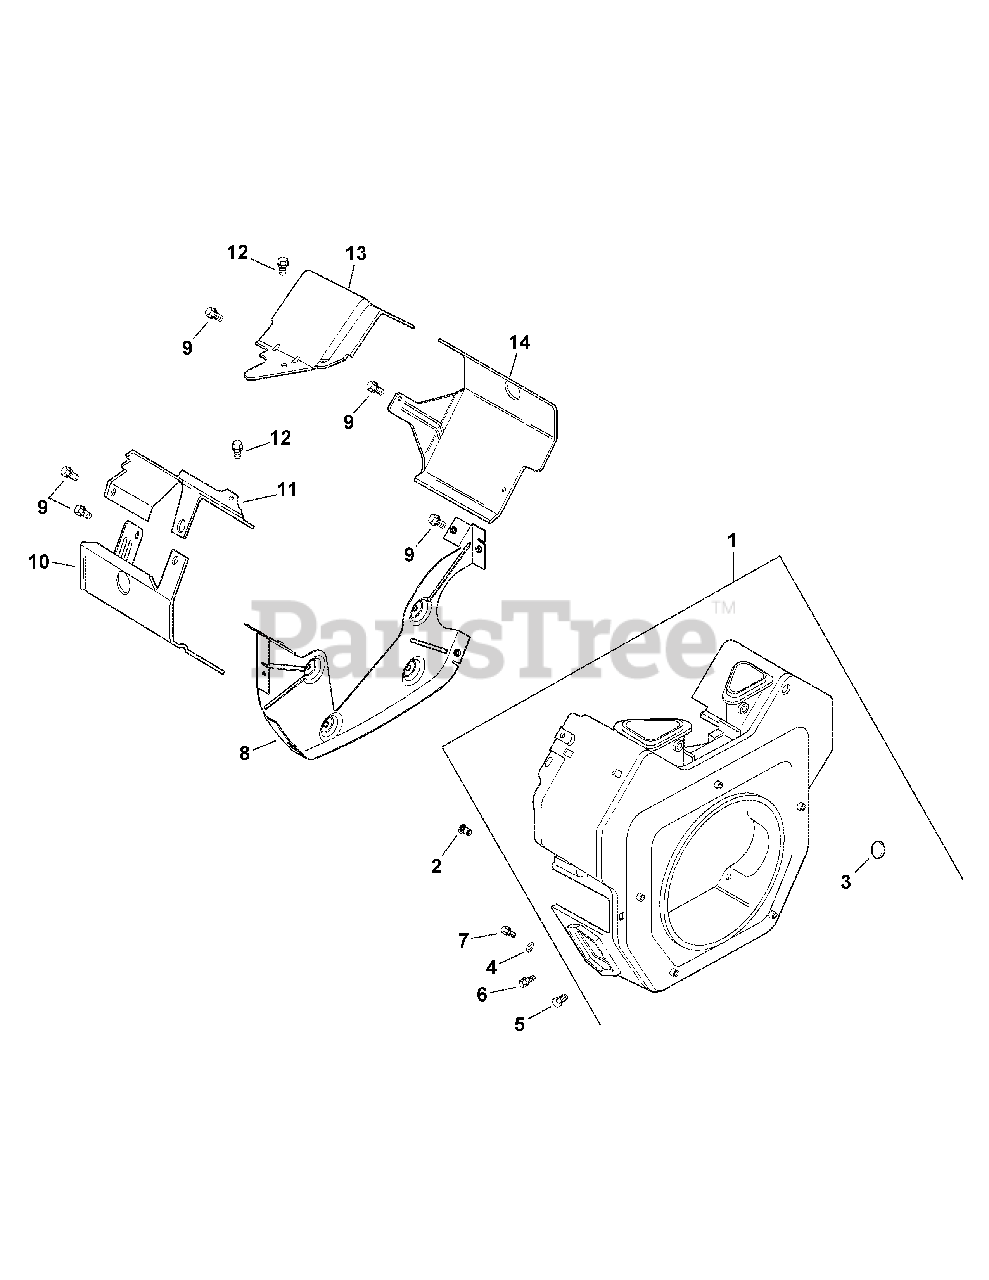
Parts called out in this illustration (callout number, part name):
1	Housing, blower
2	Insert, threaded
4	Washer, flat, 7/32"
5	Screw, hex. Flange M5x0.8x16
6	Screw, hex. Flange M5x0.8x16
7	Screw, hex. Flange M5x0.8x20
8	Plate, back (Incl KH-25-154-11-S)
9	Screw, hex flng M6x1.0x16
10	Baffle, cyl barrel #2 side
11	Baffle, valley - #2 side
12	Screw, hex flange M5x0.8x10
13	Baffle, valley - #1 side
14	Baffle, cylinder barrel - #1 side
